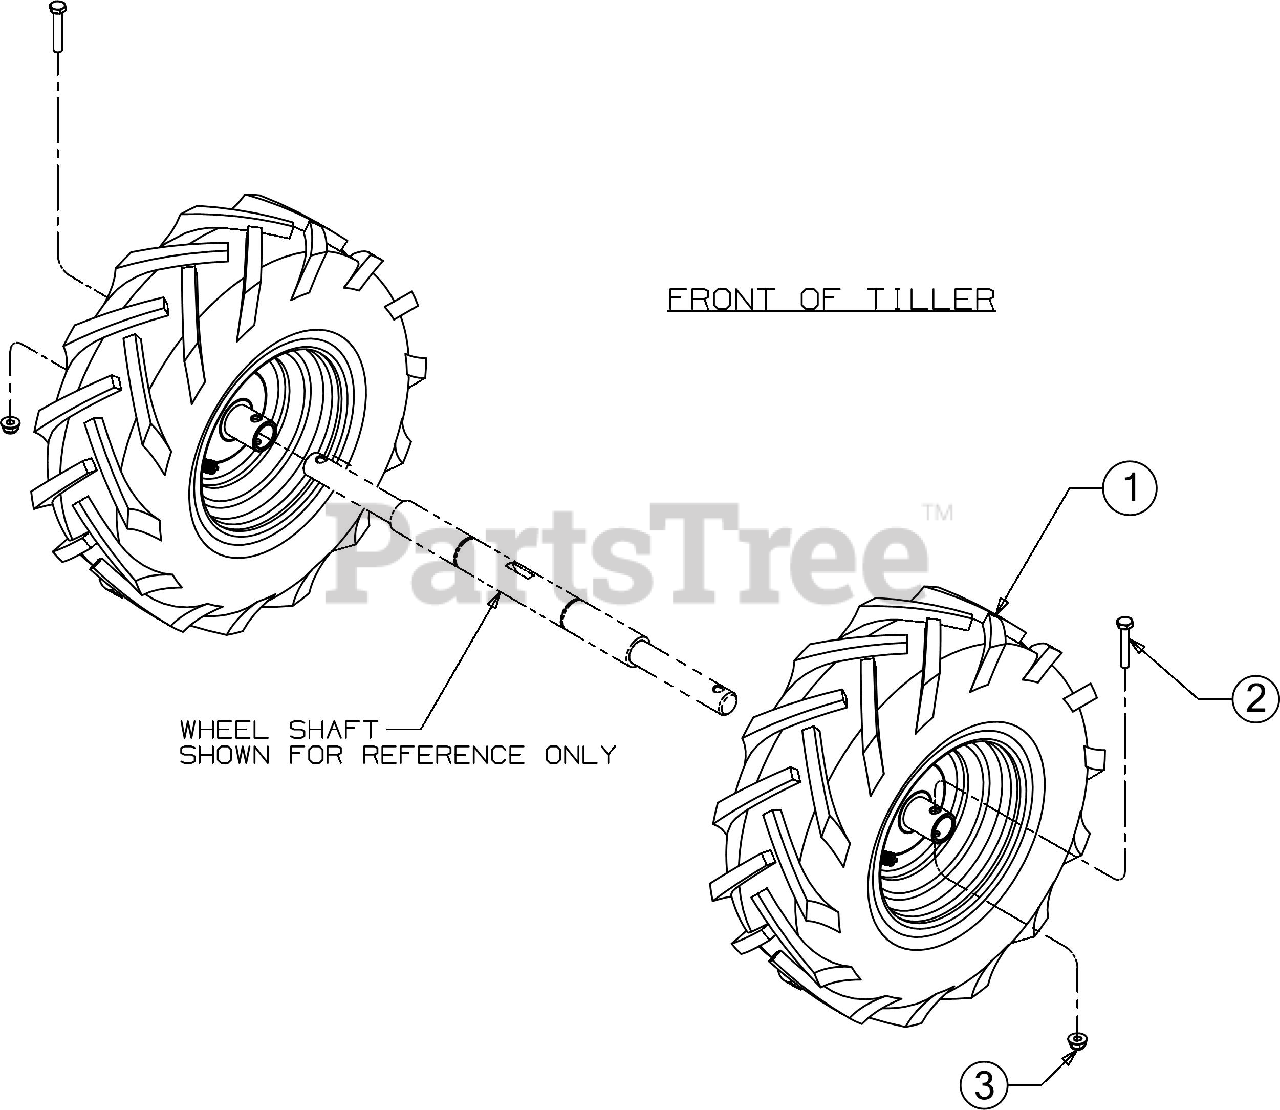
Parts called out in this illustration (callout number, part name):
1	WHEEL ASSEMBLY (13 x 5-6) (BEIGE)
2	SCREW 1/4-20 x 1.50 GR8
3	FLANGE LOCK NUT
